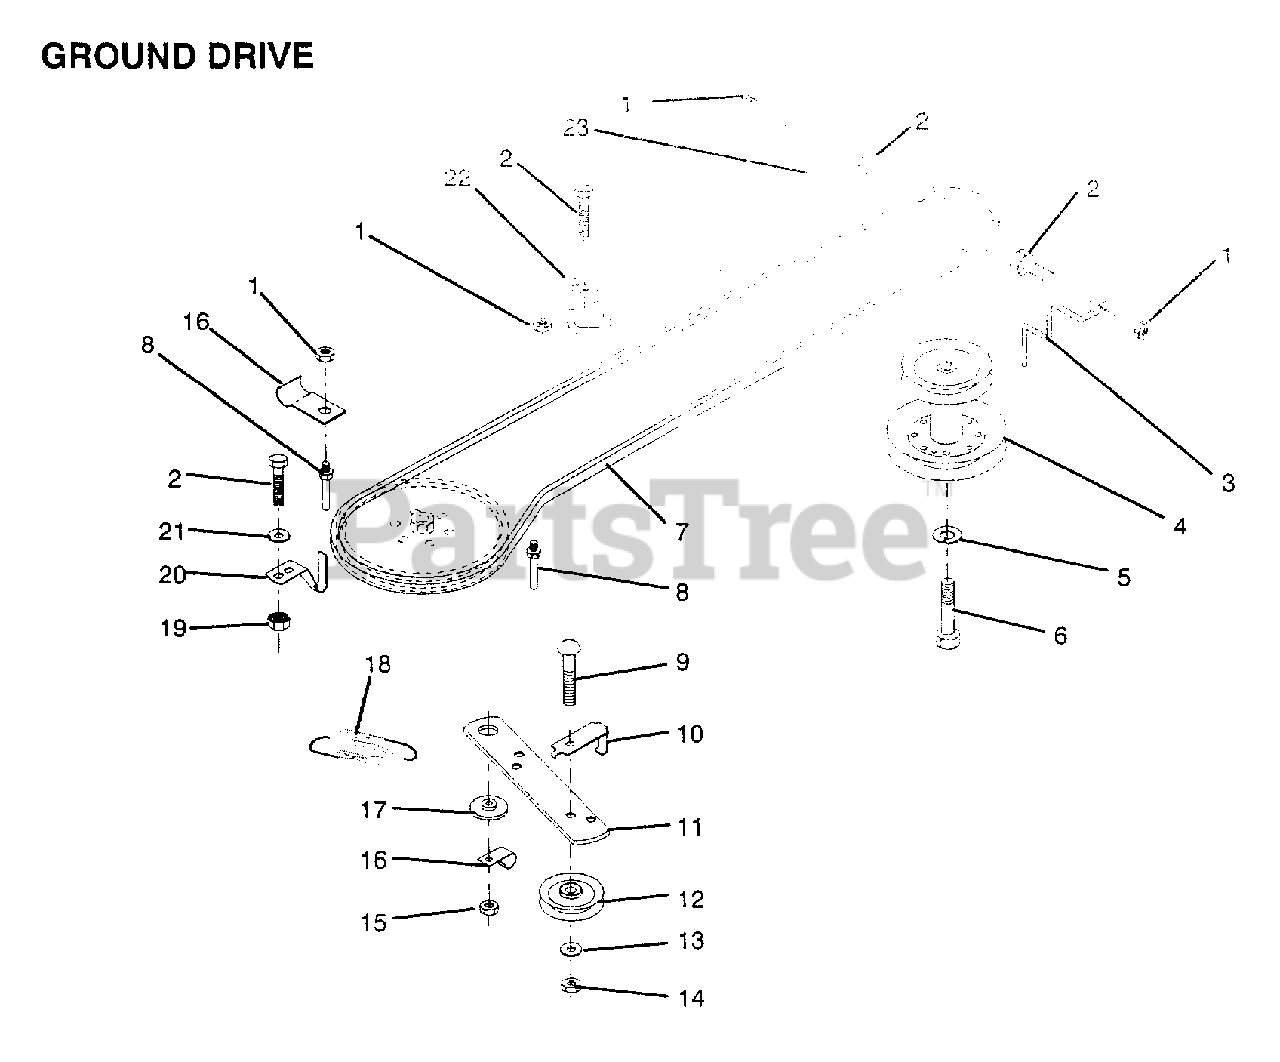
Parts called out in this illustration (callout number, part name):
2	BOLT
3	KEEPER ENG BEL LH
5	LOCKWASHER
6	BOLT
7	BELT
8	"KEEPER,DRIVE BELT"
9	BOLT
10	"KEEP,IDLER DR BEL"
13	WASHER
14	LOCKNUT
16	"CLIP,INSULATOR"
17	SPACER RETAINER
20	"KEEPER,DR BELT "
21	WASHER
22	"KEEPER,FRA DR BEL"
23	KEEPER ENG DR RH
